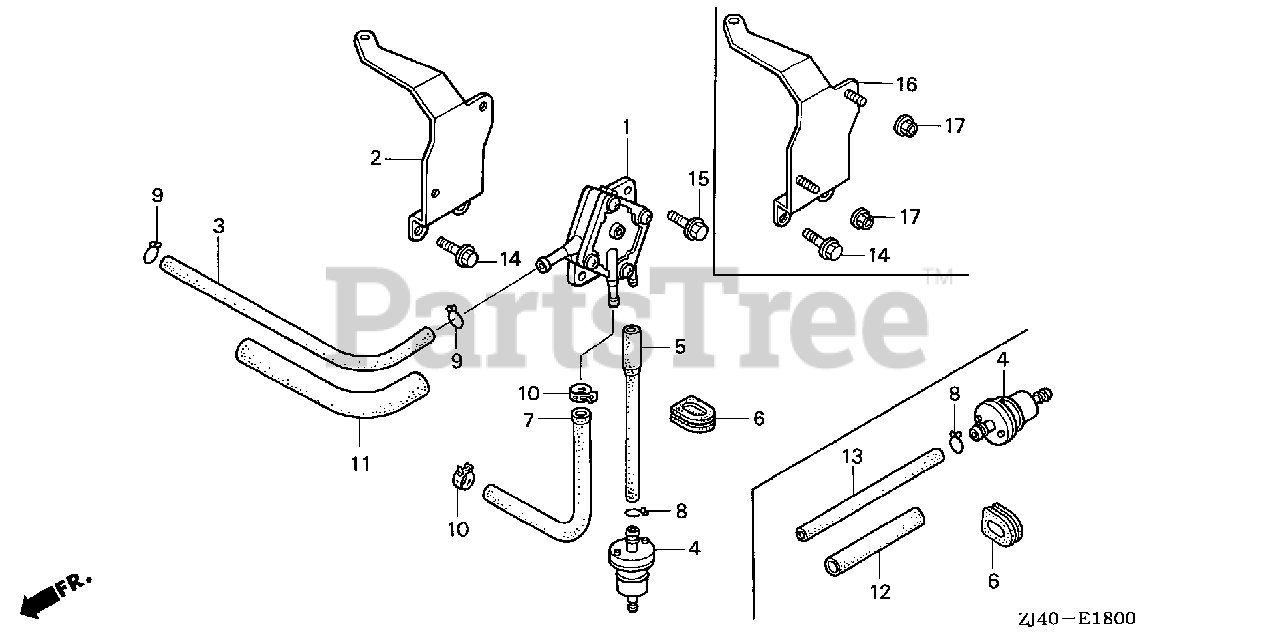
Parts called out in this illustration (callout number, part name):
1	PUMP ASSY., FUEL
2	STAY, FUEL PUMP *R8* (BRIGHT RED)
3	TUBE, FUEL
4	STRAINER, FUEL
5	TUBE B, FUEL
5	TUBE, FUEL
6	GROMMET, CORD
7	BULK HOSE, FUEL (5.5X3000) (5.3X205)
8	CLIP, TUBE (B8)
9	CLIP, TUBE (B10)
10	CLAMP, TUBE (D10.5)
11	BULK HOSE, VINYL (11X13X3000) (11X13X160)
14	BOLT, FLANGE (6X8)
15	BOLT, FLANGE (6X14)
16	STAY, FUEL PUMP *R8* (BRIGHT RED)
16	STAY, FUEL PUMP *NH1* (BLACK)
17	NUT, FLANGE (6MM)
